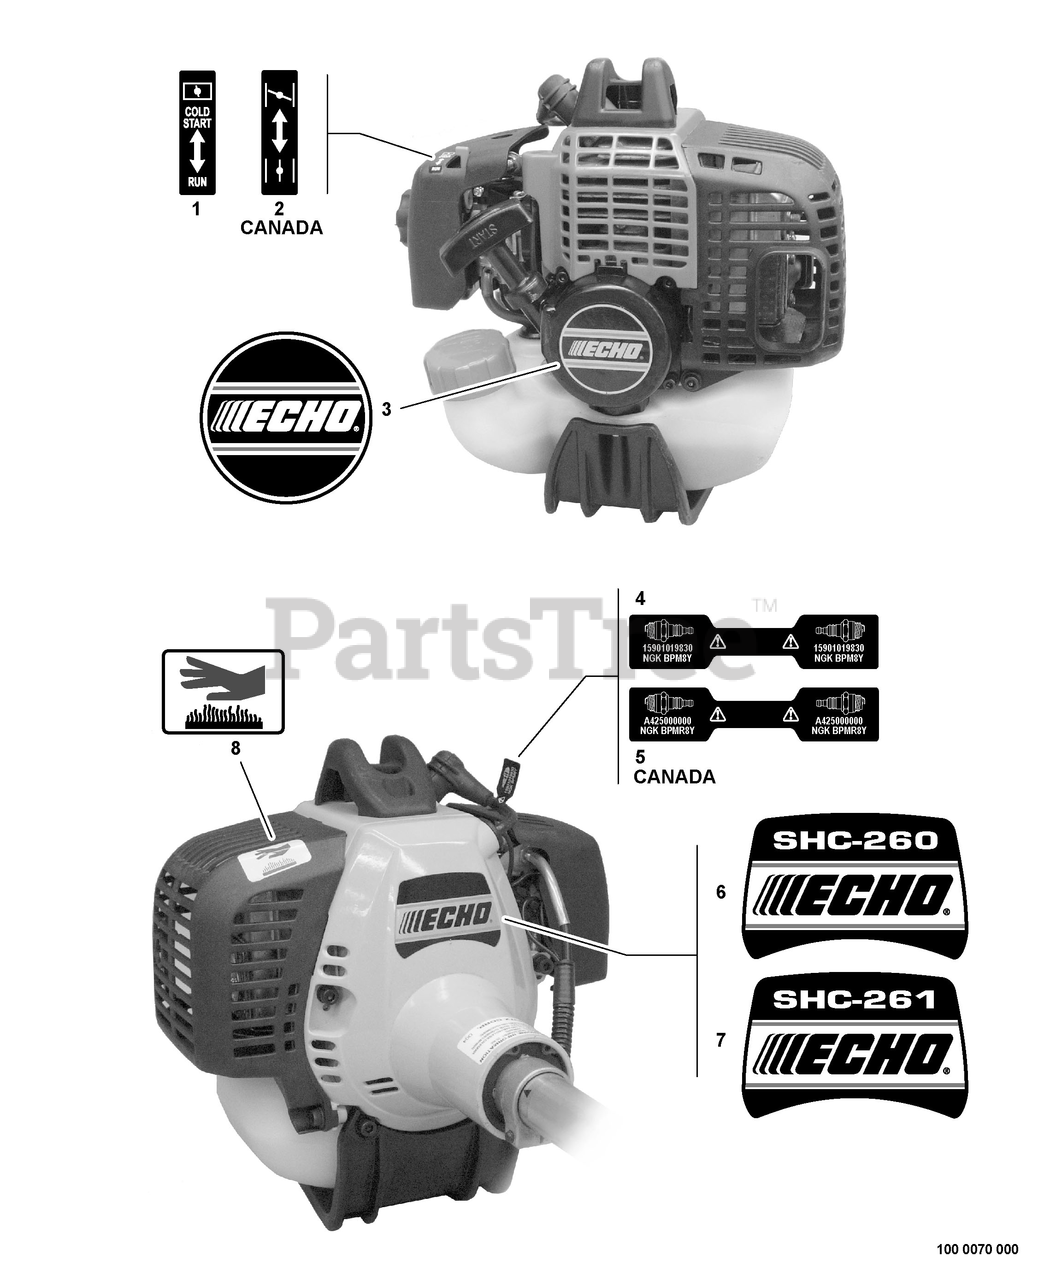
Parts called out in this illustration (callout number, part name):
1	LABEL - CHOKE
2	LABEL - CHOKE
3	LABEL - ECHO
4	LABEL - SPARK PLUG -- BPM-8Y
5	LABEL - SPARK PLUG -- BPMR-8Y
6	LABEL - MODEL SHC-260
7	LABEL - MODEL SHC-261
8	LABEL - HOT SURFACE
